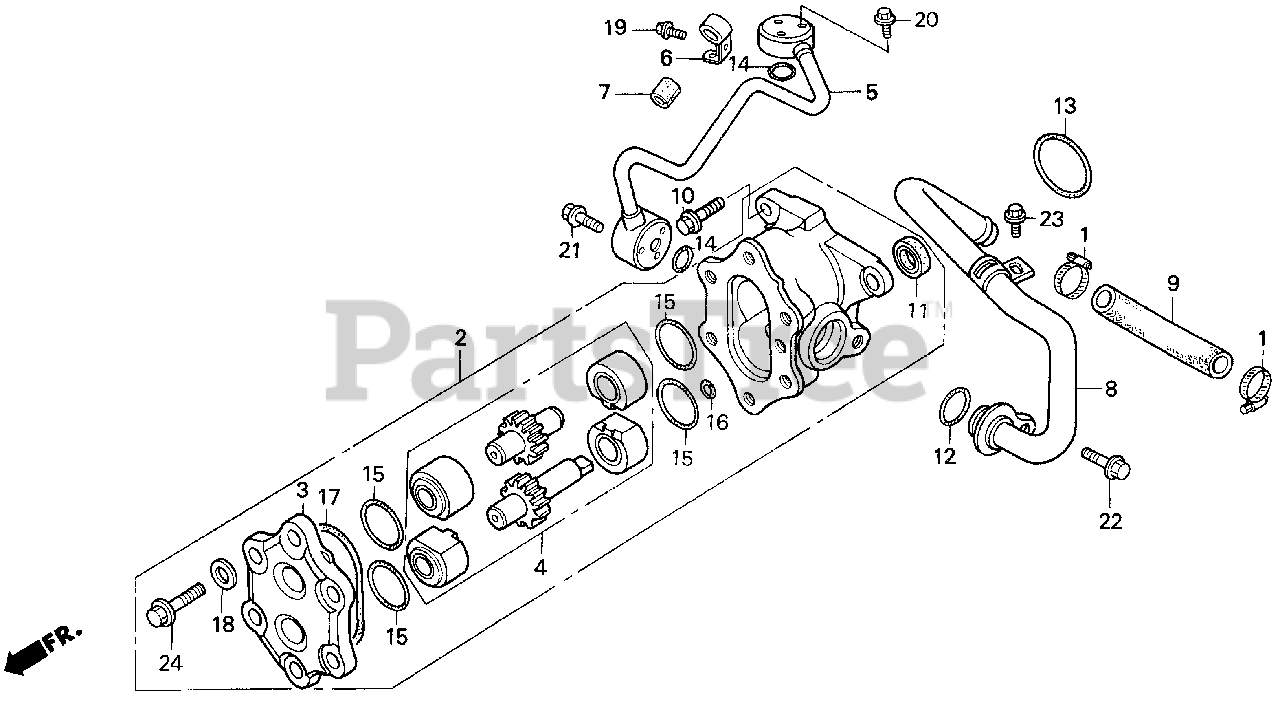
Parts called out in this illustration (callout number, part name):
1	CLAMP, WATER HOSE
2	PUMP ASSY., HYDRAULIC
3	COVER, PUMP
4	PUMP ASSY., SUB
5	PIPE, FEED
6	CLAMP, FEED PIPE
7	TUBE (12X28)
8	PIPE, INLET
10	BOLT, FLANGE (8X28)
11	OIL SEAL (16X30X7)
12	O-RING (21.5X2) (ARAI)
13	O-RING (37.5X2)
14	O-RING (10.8X2.4)
15	O-RING (23.5X2.0)
16	O-RING (4.8X1.9)
17	O-RING (53.8X3.1)
18	WASHER, PLAIN (8MM)
19	BOLT, FLANGE (6X10)
20	BOLT, FLANGE (6X30)
21	BOLT, FLANGE (6X32)
22	BOLT, FLANGE (8X16)
23	BOLT, FLANGE (8X18)
24	BOLT, FLANGE (8X30)
